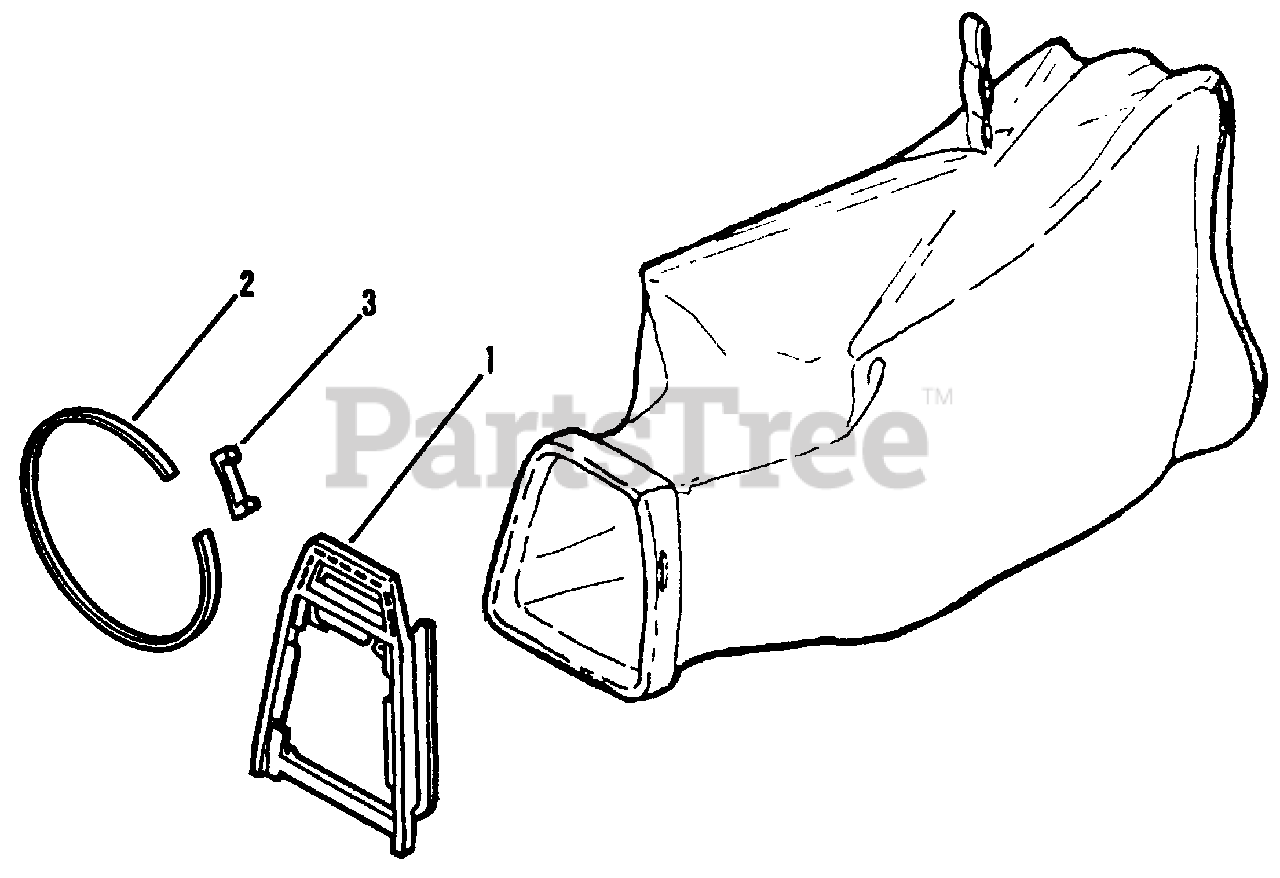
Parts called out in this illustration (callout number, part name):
1	Chute Adaptor
2	Strap and Lock
3	Strap Lock
